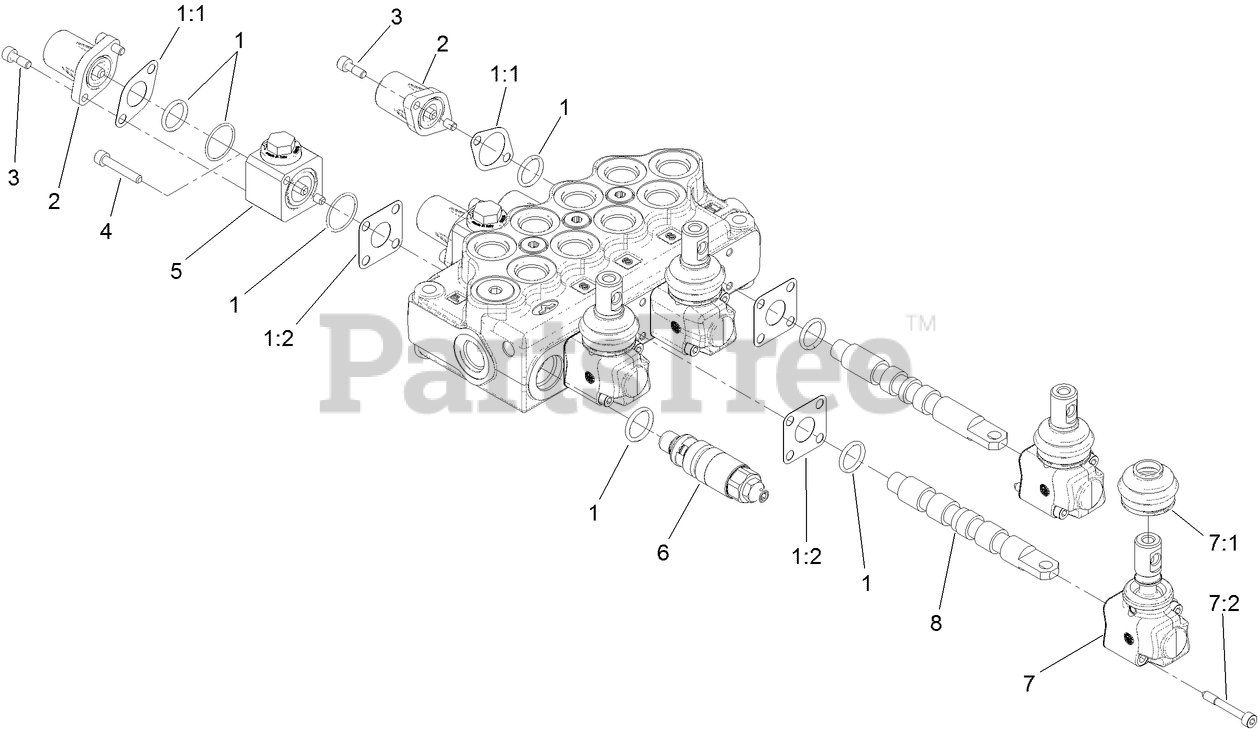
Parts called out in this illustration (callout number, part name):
1	SEAL KIT
1:1	GASKET
1:2	GASKET
2	HIGH FORCE SPRING KIT
2	STANDARD SPRING KIT
3	SCREW-CAP, END
5	BLOCK-SWITCH, MOUNT
6	VALVE-RELIEF
7	OPERATOR ASM
8	VALVE-SPOOL
